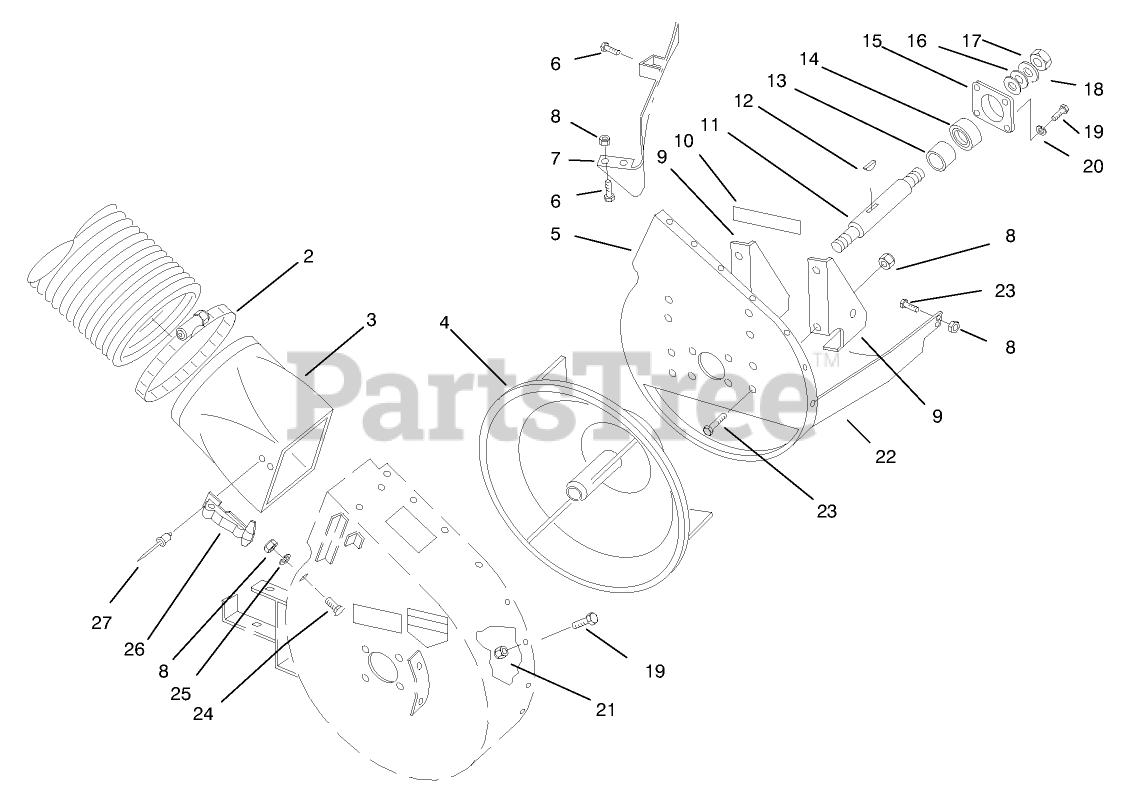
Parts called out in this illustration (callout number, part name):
2	CLAMP
3	ADAPTER
4	IMPELLER - WELDED BLACK
5	ASM - MTG PLATE W/DECALB
6	SCREW
7	BAFFLE W.A. B
8	NUT-LOCK, NI
9	BRACKET-BLOWER MT B
10	DECAL
11	SHAFT- BLOWER
13	SPACER
14	BEARING-BALL
15	CUP-BEARING
16	WASHER-FLAT
17	NUT 5/8-11 L.H.
18	WASHER-FLAT
19	SCREW-HH
20	WASHER-LOCK
21	NUT-LOCK, NI
22	DEFLECTOR-BLOWER B
23	SCREW-HH
24	BOLT-CARR
25	WASHER-PLAIN
26	HANDLE ASM
27	RIVET-POP
